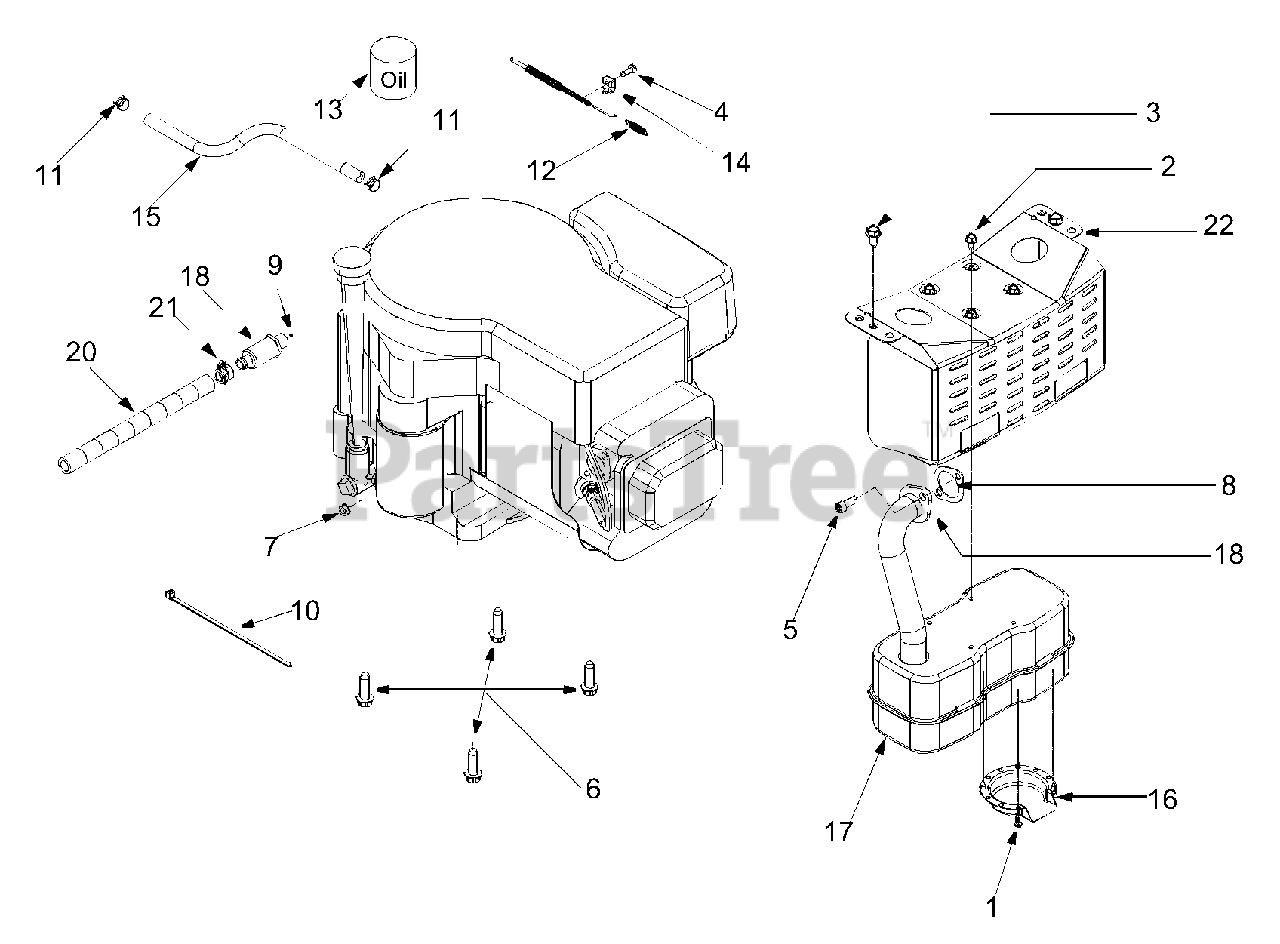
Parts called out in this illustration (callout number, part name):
1	AB Screw #8-18 x 0.5
2	TT Screw 1/4-20 x 0.5
3	AB Screw 5/16-12 x 0.5
4	T screw #10-32 x 0.625
5	Socket Head Screw 5/16-18 x .750
6	TT Screw 3/8-16 x 1.25
8	Exhaust Gasket
9	Sealant: Loctite(TM)
12	Extension Spring
13	SAE 30W Oil
14	Throttle Clamp
15	Fuel Line Hose
16	Muffler Deflector
17	Muffler
18	Exhaust Pipe
20	OIl Drain Hose extension
21	Oil Drain Cap
